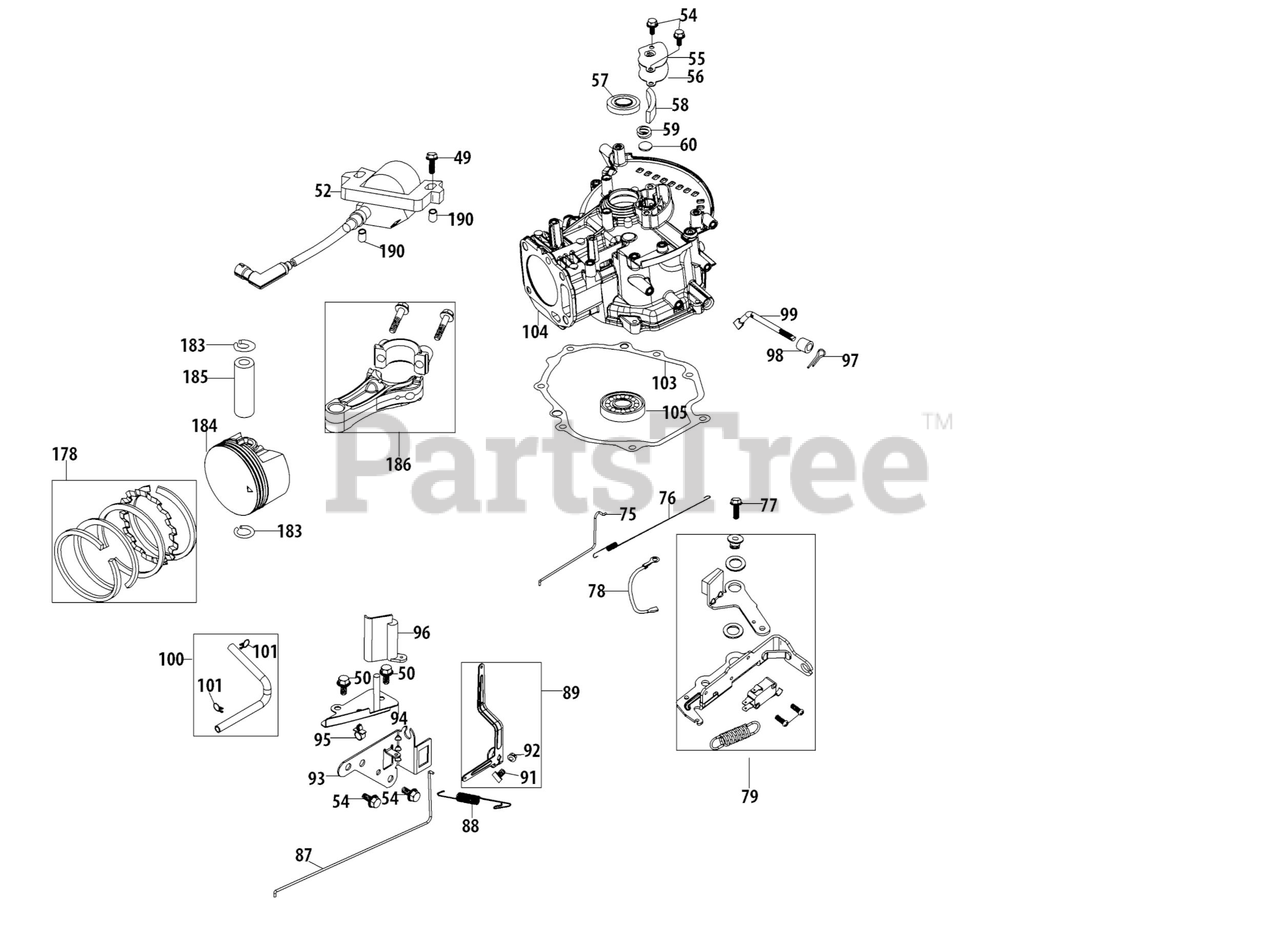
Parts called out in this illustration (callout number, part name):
49	Bolt M6X28 T/X/P Crankcase/Dp Stick
50	Bolt M6X12 Multi-Purpose
52	Ignition Coil Assembly
54	Bolt M6X14 Multi-Purpose
55	Breather Cover Plate
56	Breather Gasket
57	Upper Crankshaft Seal
58	Breather Screen
59	Breather Valve Spring
60	Breather Valve
75	Choke Linkage
76	Throttle Linkage Spring
77	Bolt M6?25 Ign/Brake/Cvr Plt
78	Grounding Wire
79	Brake Assembly
87	Throttle Linkage
88	Governor Spring
89	Governor Arm Assembly
91	Governor Arm Bolt
92	Governor Arm Nut M6
93	Component Bracket
94	Air Vane Bracket
95	Plastic Support Clamp
96	Air Vane
97	Governor Arm Shaft Cotter Pin
98	Governor Seal
99	Governor Arm Shaft
100	Breather Hose Assembly
101	Breather Hose Clamp
103	Crankcase Cover Gasket
104	Crankcase
104	(Mtd Srvc Kit) Short Block
105	Main Bearing
178	Piston Ring Set
183	Piston Pin Snap Ring
184	Piston
185	Piston Pin
186	Connecting Rod Assembly
190	Ignition Coil Spacer
